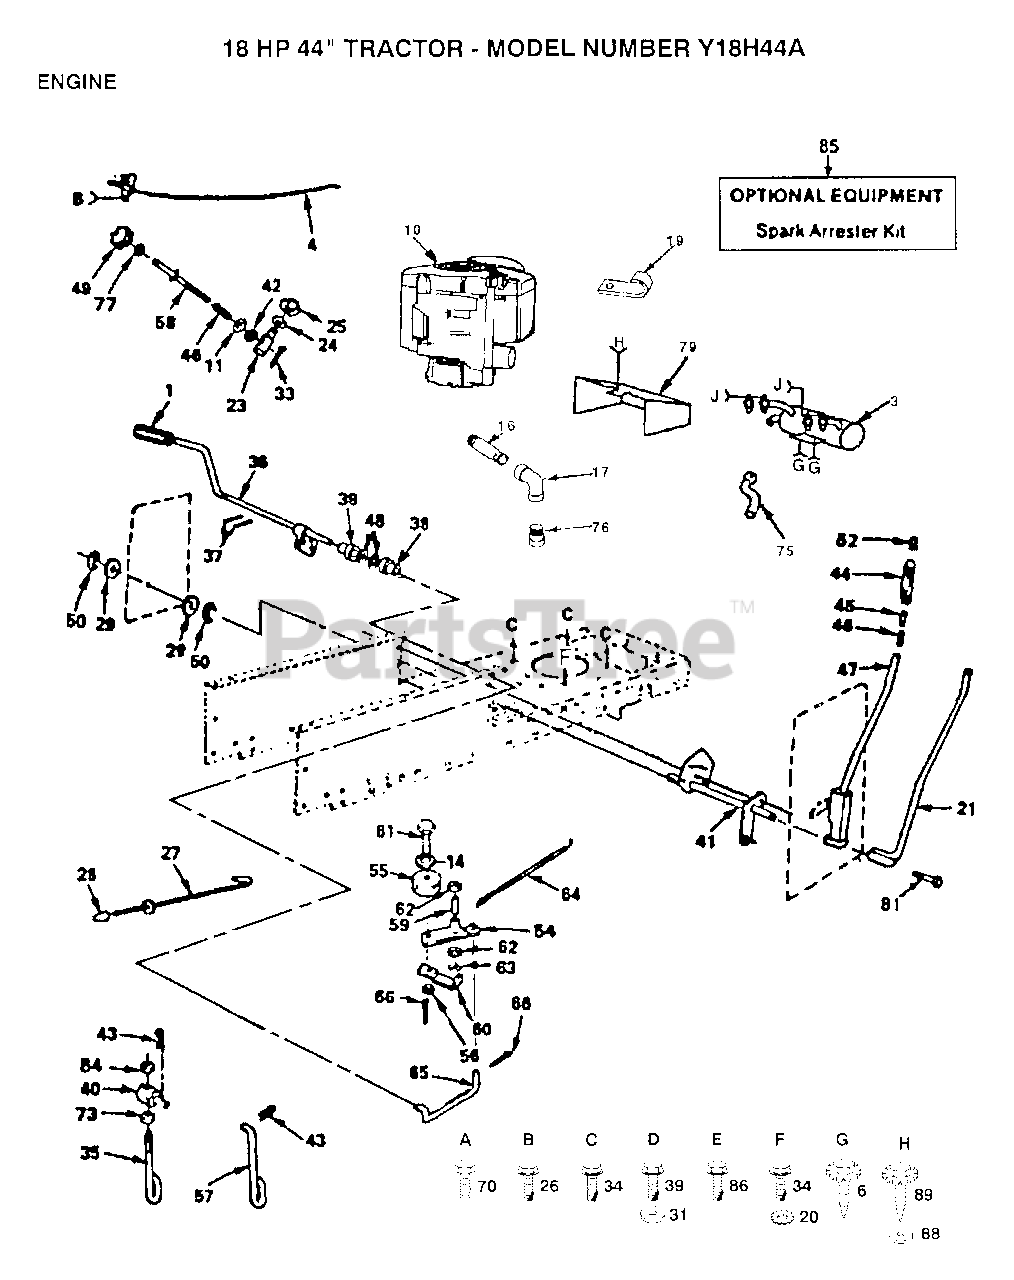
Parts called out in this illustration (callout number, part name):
1	PEDAL COVER T
4	"CONTROL,THROTTLE"
7	LOCKWASHER
8	WASHER PM
11	WASHER
14	WASHER
16	PIPE NIPPLE LT
17	ELBOW
19	MUFFLER CLAMP
20	LOCKWASHER
21	LEVER ROD LT
23	TRUNION LT
24	WASHER
25	KLIP RING
26	SCREW LT
27	BRAKE PARK ROD
28	PLUNGER CAP T
29	WASHER
34	SCREW LT
35	PIVOT PIN T
38	NYLON BEARING
41	LIFT SHAFT ASM
42	NUT T
44	GRIP
46	SPRING T
48	WASHER LT
50	E-RING
54	ARM IDLER
57	LIFT LINK LT
58	ROD LIFT LT
59	"LY, BEARING"
60	RETAIN BELT
62	WASHER LT
63	KLIP RING
64	"SPRING, RETURN LT"
65	"LINK, CLUTCH T"
66	COTTER PIN
73	NUT
74	SCREW
77	NUT
81	"BOLT,HEX"
